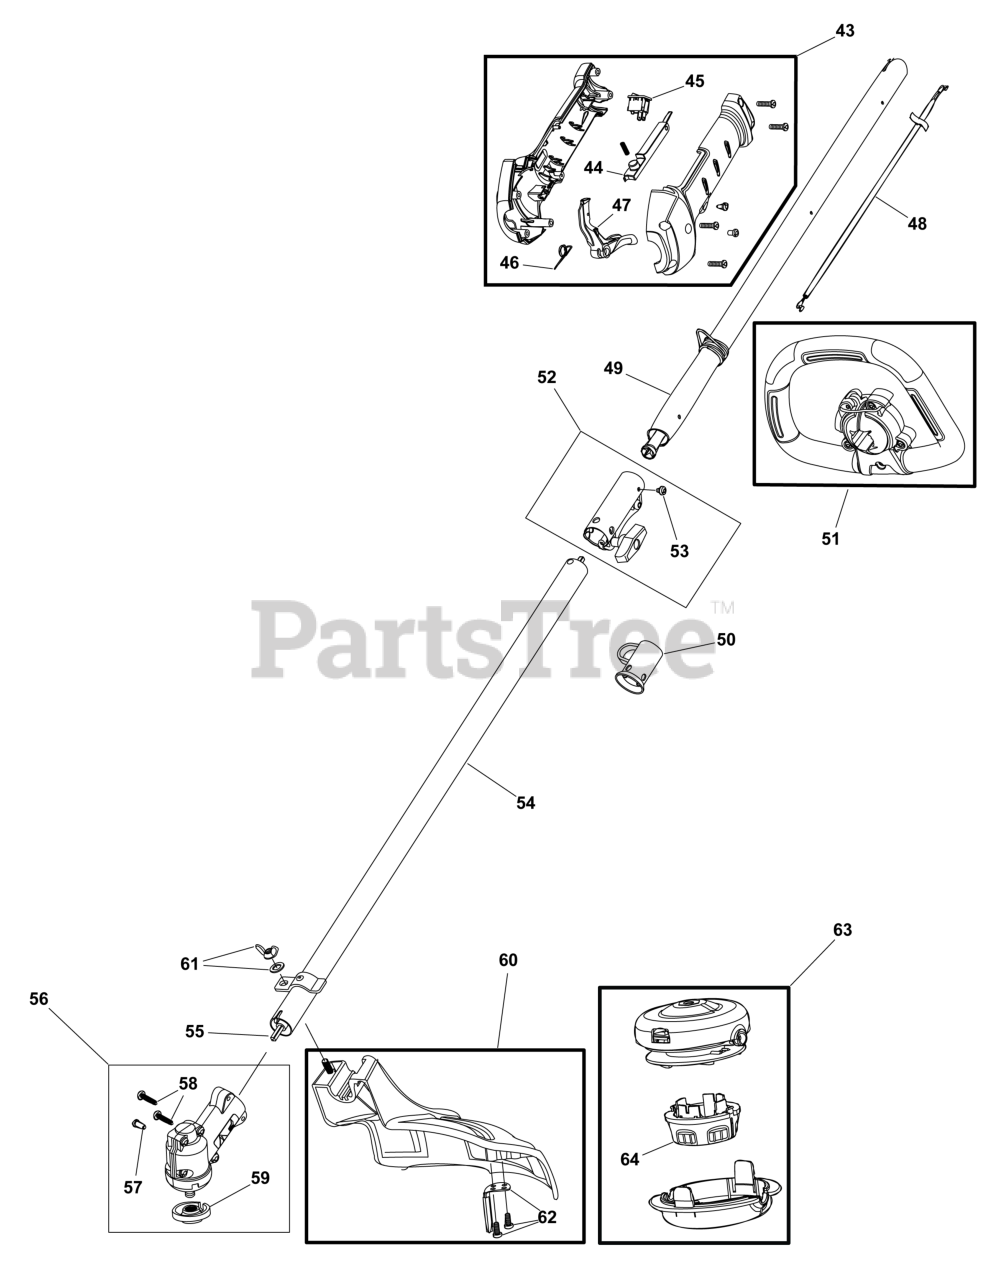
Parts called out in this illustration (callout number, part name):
43	KIT, Throttle Housing
44	THROTTLE Trigger Lock Out
45	ASSY, TRIGGER SWITCH
46	THROTTLE Trigger Spring
47	THROTTLE Trigger
48	ASSY, THROTTLE Cable
49	ASSY, UPPER Shaft Housing
50	HANGER
51	KIT, Handle
52	SPLIT Boom Coupler
53	SCREW, Anti-ROTATION
54	ASSY, Lower Shaft Housing
55	LOWER Flexible Drive Shaft
56	ASSY, Gearbox
57	SCREW, Anti-Rotation
58	HARDWARE, Gearbox Mounting
59	CUTTING HEAD Driver
60	ASSEMBLY, Shield
61	HARDWARE, Shield Mounting
62	ASSY, Blade
63	ASSY, Cutting Head
64	KNOB, Bump
